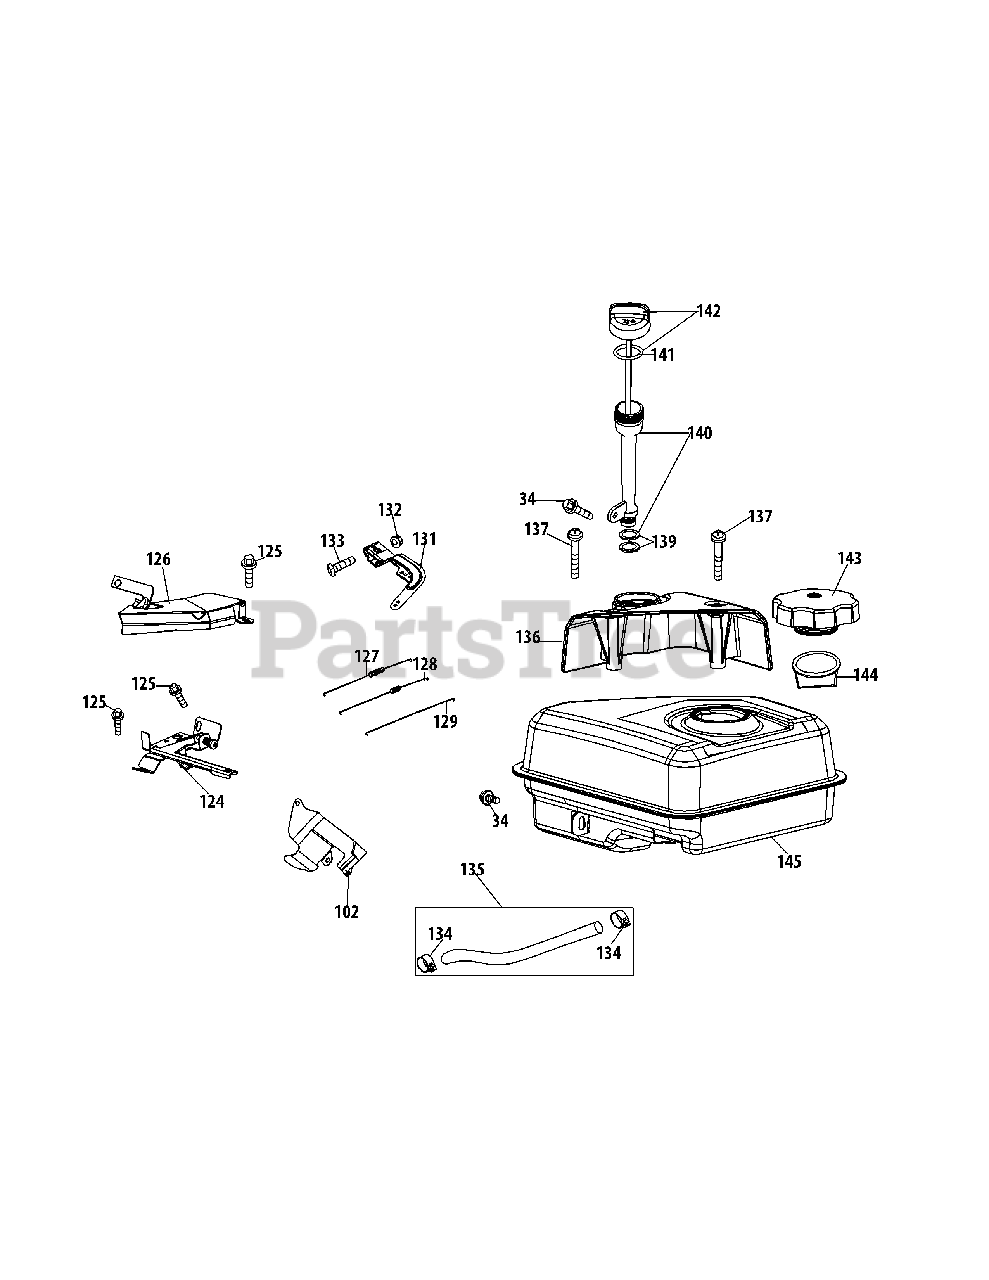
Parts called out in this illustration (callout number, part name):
34	Bolt M6×12
102	Air Shield
124	Throttle Bracket
125	Bolt M6×12
126	Governor Linkage Shield
127	Governor Spring
128	Throttle Linkage Spring
129	Throttle Linkage
131	Governor Arm
132	Nut M6
133	Governor Arm Bolt
134	Fuel Hose Clamp
135	Fuel Line Kit
136	Dipstick Decoration Cover
139	Oil Fill Tube O-Ring
140	Oil Fill Tube Assembly
141	Dipstick O-Ring
142	Dipstick Assembly
143	Fuel Cap Assembly
144	Fuel Filter
145	Fuel Tank Assembly
